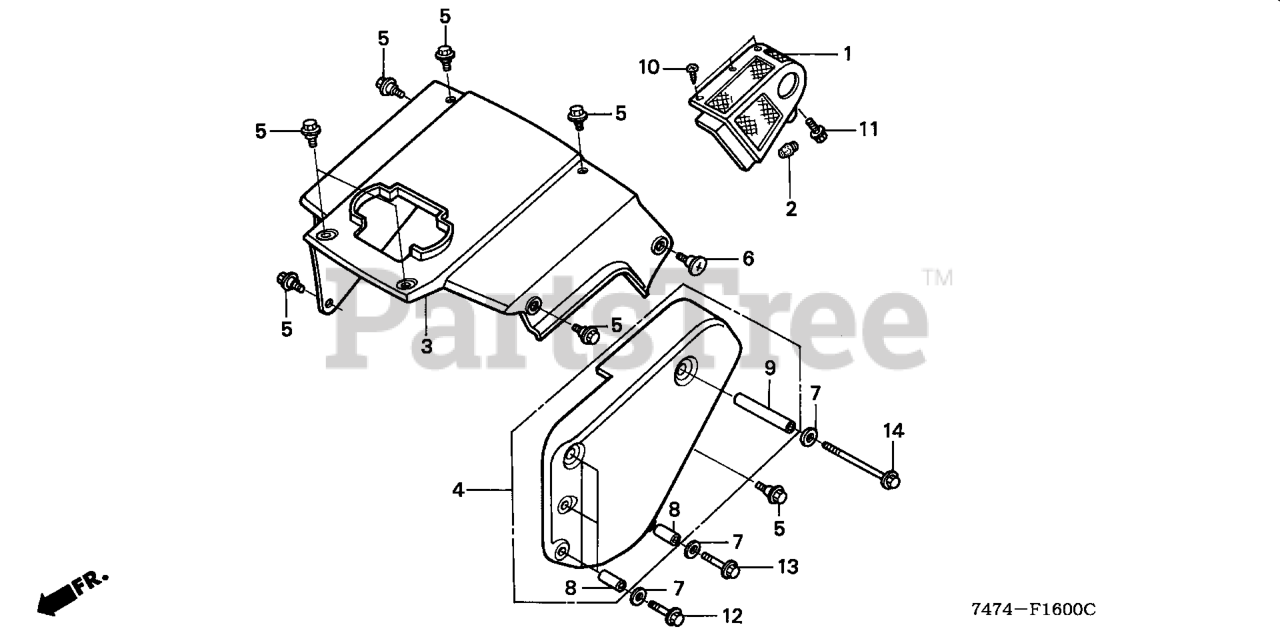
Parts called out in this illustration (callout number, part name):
1	PROTECTOR, MUFFLER *NH105* (MAT BLACK)
3	COVER, FR. *R280* (POWER RED)
4	COVER, BELT *R280* (POWER RED)
5	BOLT, FLANGE (6MM) (BLACK)
6	SCREW, METER VISOR SETTING
7	WASHER (6MM)
8	COLLAR A, BELT COVER
9	COLLAR B, BELT COVER
10	SCREW, TAPPING (5X10)
11	BOLT, FLANGE (6X16) Use from Engine SN 2056820.
12	BOLT, FLANGE (6X32) Use from Frame SN 1003299.
13	BOLT, FLANGE (6X35)
14	BOLT, FLANGE (6X85)
